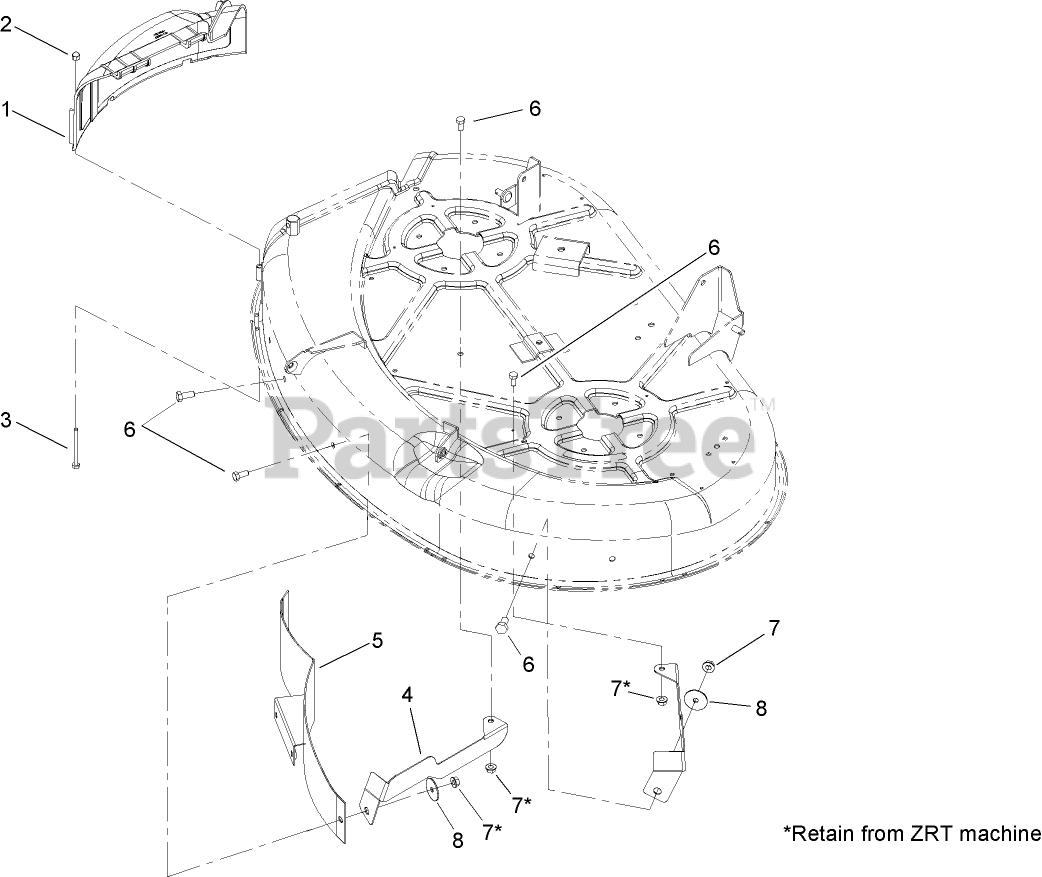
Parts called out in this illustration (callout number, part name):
1	COVER-DISCHARGE, DECK
2	NUT-CAP
3	SCREW-HH
4	BAFFLE-MULCH
5	BAFFLE-FRONT, RIGHT
6	SCREW-HH
7	NUT-HF
8	WASHER-FLAT
